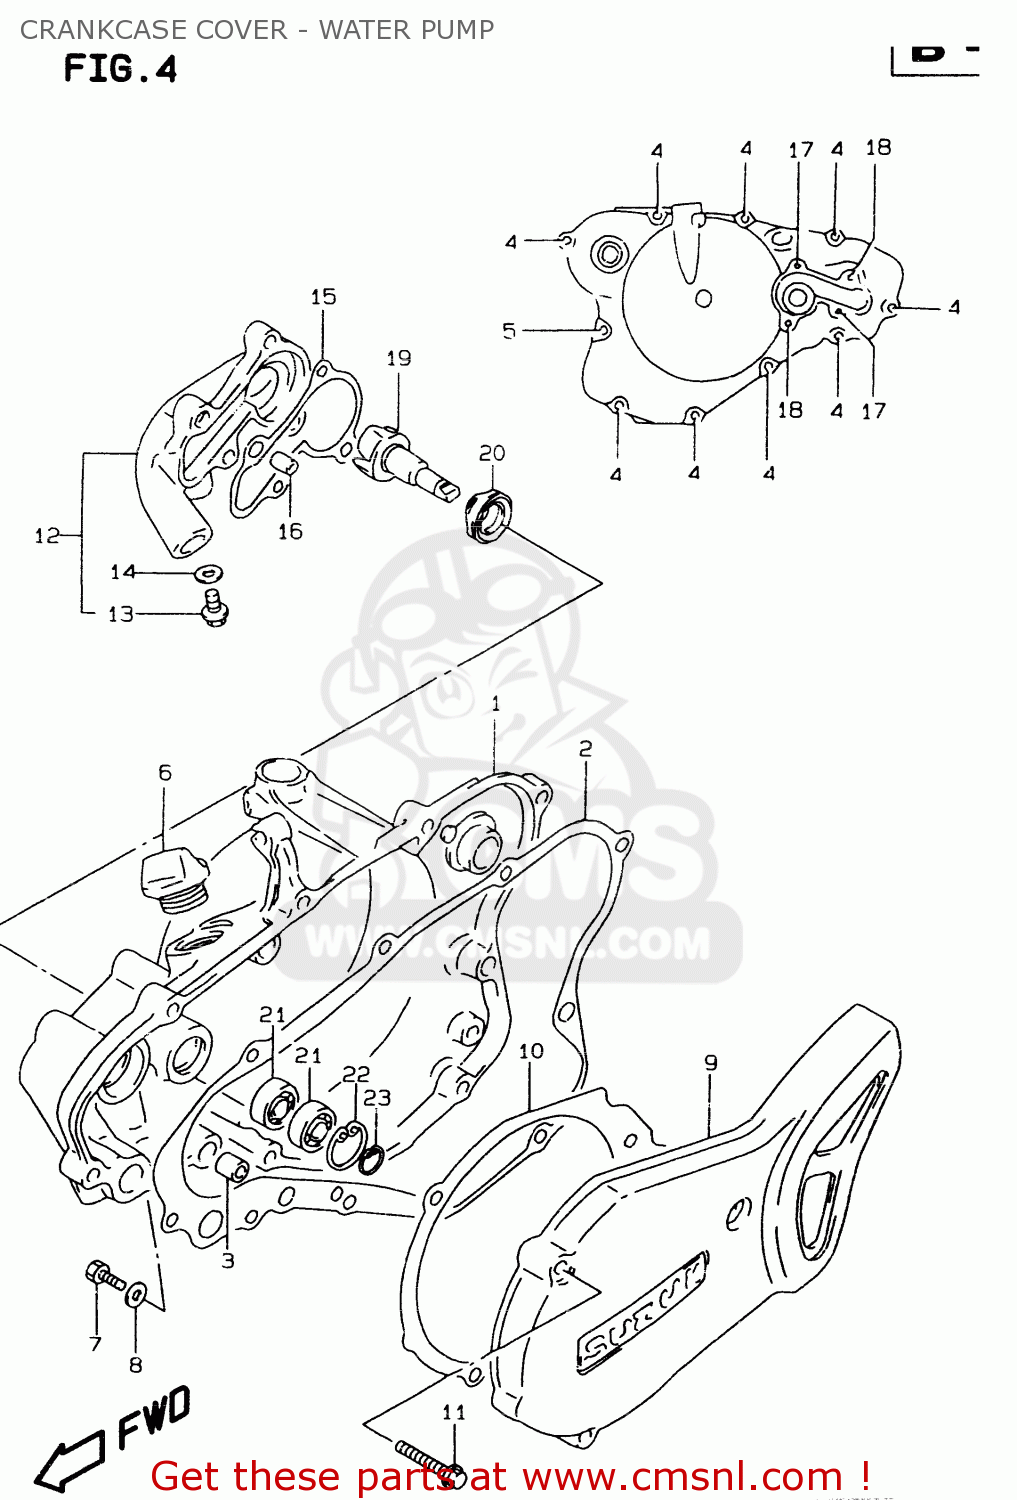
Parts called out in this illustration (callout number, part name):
1	COVER,CLUTCH
2	GASKET,CLUTCH COVER (NAS)
3	PIN
4	SCREW
5	BOLT
6	PLUG SET
7	SCREW(6X10)
8	GASKET(6.2X11X1).2 (NAS)
9	COVER,MAGNETO
10	GASKET,MAGNETO COVER (NAS)
11	SCREW
12	CASE,WATER PUMP
13	BOLT
14	WASHER
15	GASKET,WATER PUMP CASE (NAS)
16	PIN
17	SCREW
18	BOLT,G/S SWITC
19	IMPELLER,WATER PUMP
20	SEAL,WATER PUMP OIL
21	BEARING
22	CIRCLIP
23	CIRCLIP
